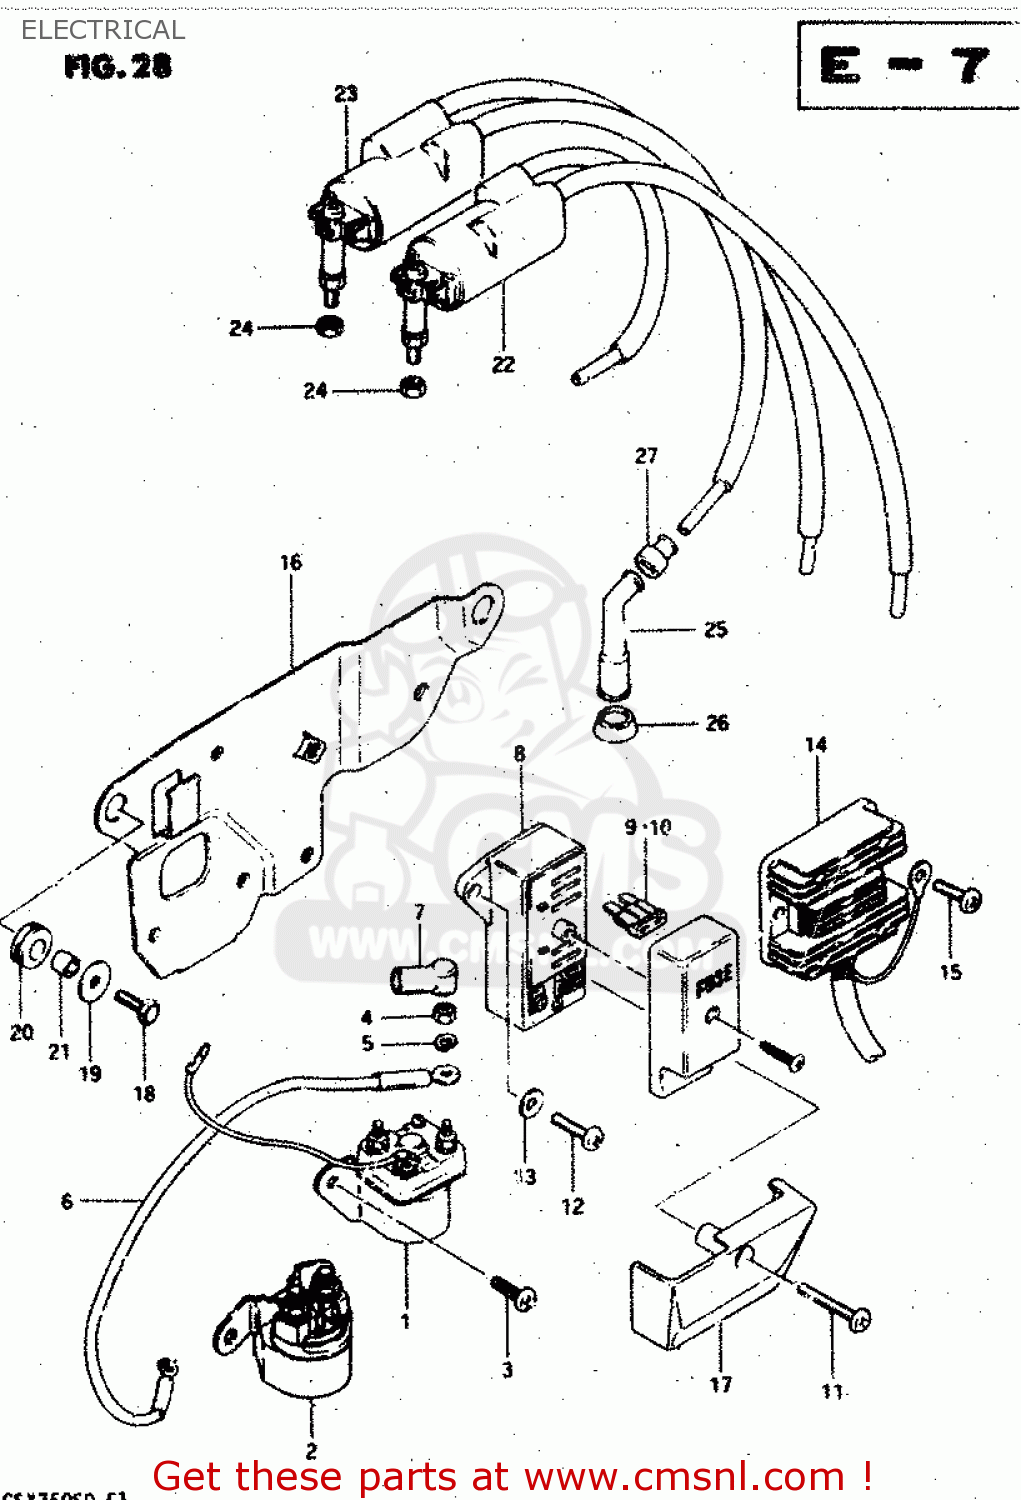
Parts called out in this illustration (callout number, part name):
1	RELAY, STARTING MOTOR
2	RELAY ASSEMBLY,STARTING MOTOR
3	SCREW
4	NUT 6MM
5	LOCK WASHER
6	CORD,BATTERY MINUS
7	CAP,STARTER RELAY
8	BOX ASSEMBLY,FUSE
9	FUSE(10A)
10	FUSE(15A)
11	SCREW
12	SCREW
13	WASHER
14	RECTIFIER ASSEMBLY
15	SCREW 6X12
16	PLATE, PARTS HOLDER
17	COVER,ELECTRIC PARTS HOLDER
18	BOLT, UPPER
19	WASHER (6.5X22X1.6)
20	CUSHION
21	SPACER (7X9X7)
22	COIL ASSEMBLY,IGNITION
23	COIL ASSEMBLY,IGNITION
24	NUT
25	CAP ASSY,SPARK PLUG
26	SEAL,SPARK PLUG
27	SEAL,SPARK PLU
